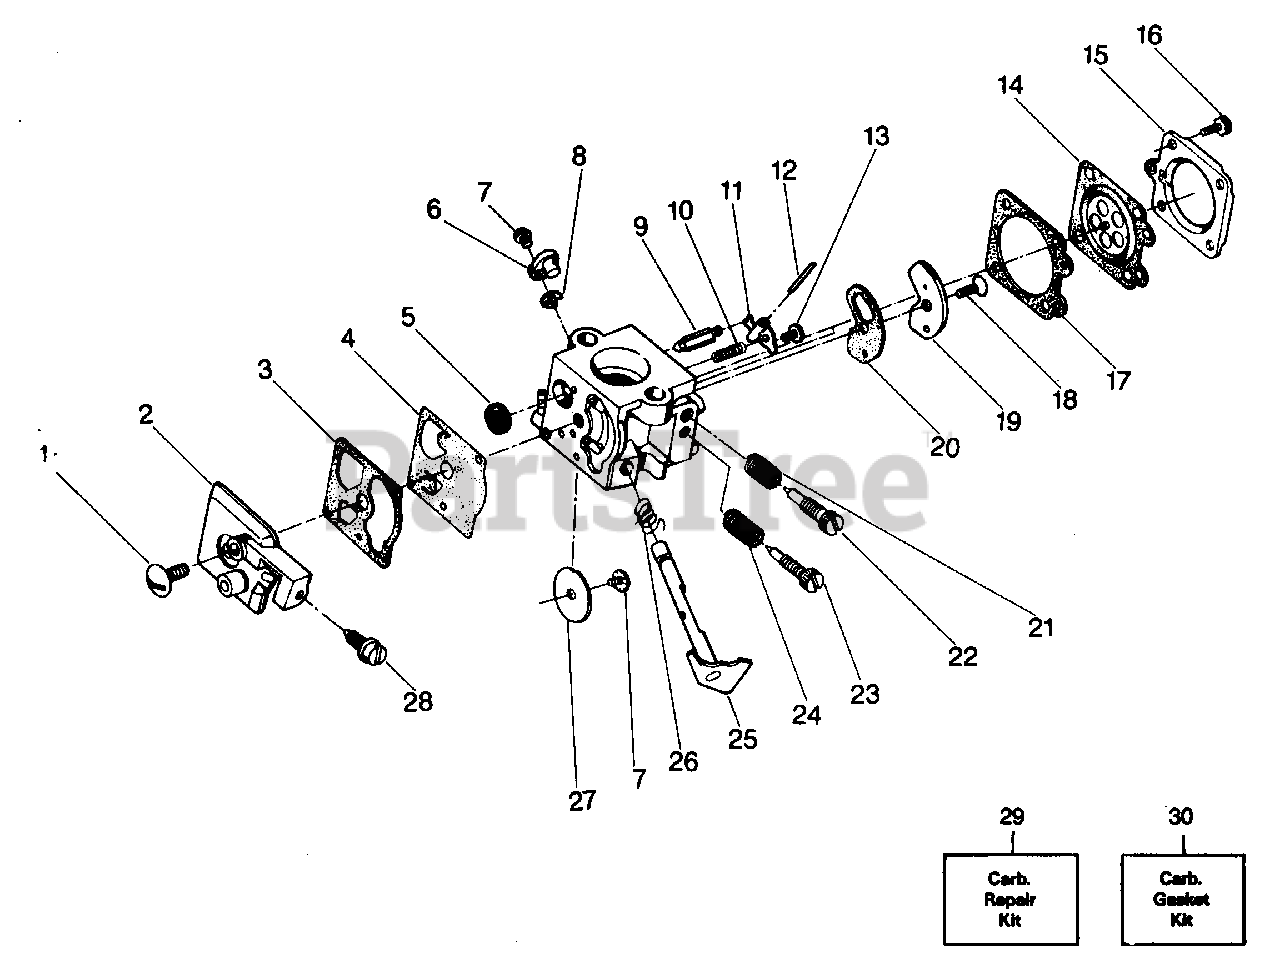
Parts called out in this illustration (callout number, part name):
1	Screw - Pump Cover
2	Pump Cover Ass'y. (Incl. #28)
3	Gasket Pump
4	Diaphragm - Pump
5	Screen - Inlet
6	Swivel Lever Ass'y.
7	Screw - Throttle Valve
8	Clip - Throttle Shaft
9	Valve - Inlet Needle
10	Spring - Metering Lever
11	Lever - Metering
12	Pin - Metering Lever
13	Screw - Metering Lever Pin
14	Diaphragm Assembly - Metering
15	Cover - Metering Diaphragm
16	Screw Assembly - Metering Cover & Throttle Shaft Clip
17	Gasket - Metering Diaphragm
18	Screw - Circuit Plate
19	Plate - Circuit
20	Gasket - Circuit Plate
21	Spring - Hi Speed Needle
22	Needle - Hi Speed
23	Needle - Idle
24	Spring - Idle Needle
25	Shaft Assembly - Throttle
26	Spring - Throttle Return
27	Valve - Throttle
28	Screw - Idle Adjustment
29	Kit - Carb Kwik Repair Kit (inc. 3-5,7,9-12,14,17,18,20)
30	Kit-Carb Gasket/Diaphragm (Inc. 3,4,14,17,20)
